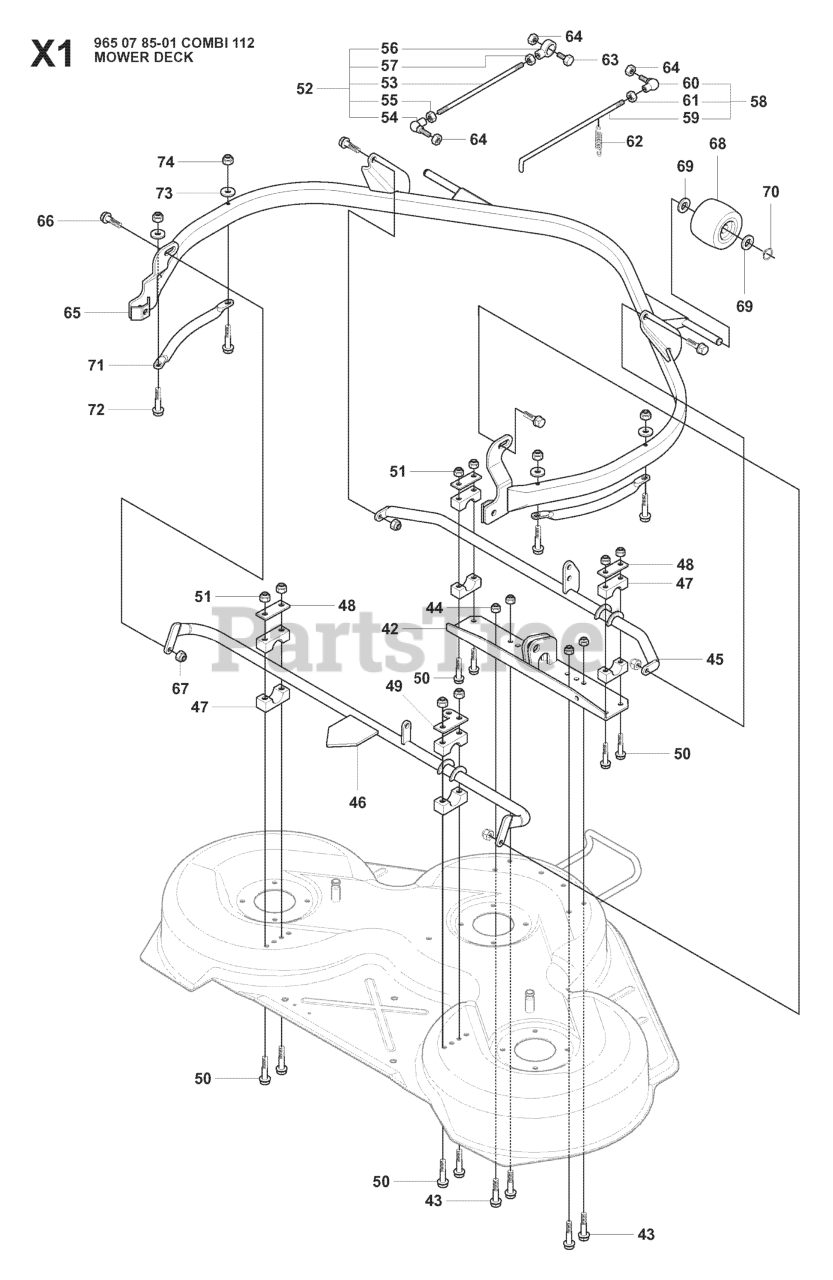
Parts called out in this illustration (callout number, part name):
44	LOCKNUT M8
51	LOCKNUT M8
52	PARALLEL RODY ASSY
57	NUT
58	CLUTCH ROD ASSY
64	NUT
67	LOCKNUT M8
68	DECK ROLLER, FRONT
70	RETAINING RING SGA 15
73	WASHER
74	LOCKNUT M6
